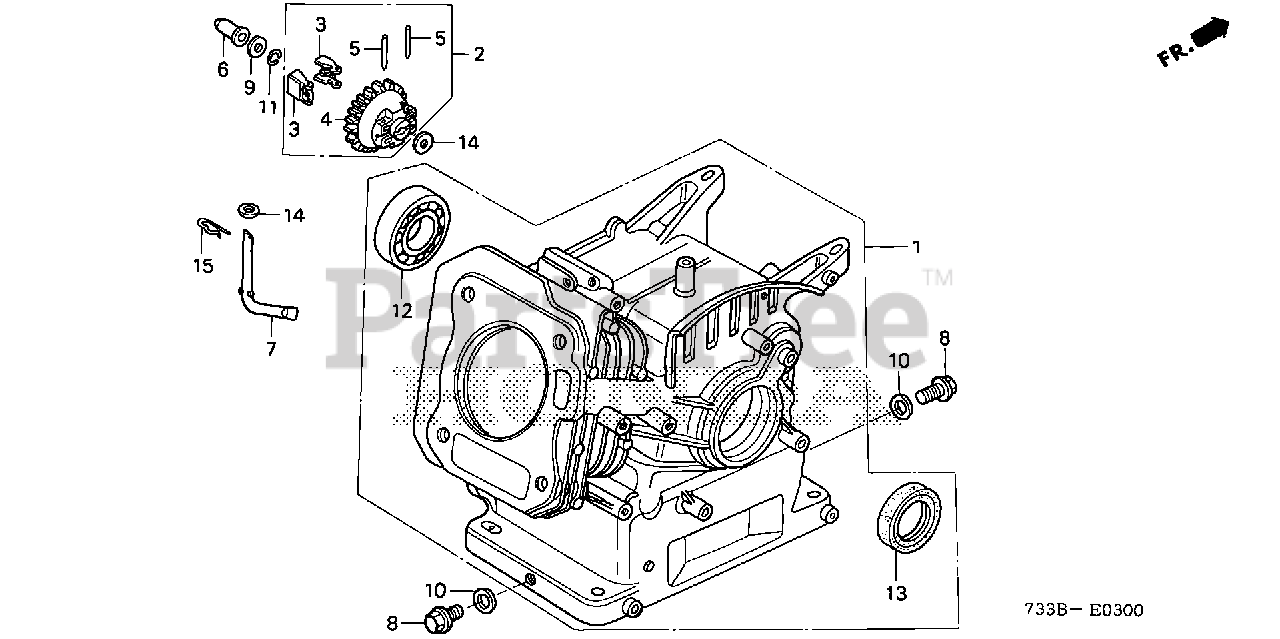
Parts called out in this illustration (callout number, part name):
1	CYLINDER ASSY.
2	GOVERNOR ASSY.
3	WEIGHT, GOVERNOR
4	HOLDER, GOVERNOR WEIGHT
5	PIN, GOVERNOR WEIGHT
6	SLIDER, GOVERNOR
7	SHAFT, GOVERNOR ARM
8	BOLT, DRAIN PLUG
10	WASHER, DRAIN PLUG (10.2MM)
11	CLIP, GOVERNOR HOLDER
12	BEARING, RADIAL BALL (6205TMB) (NTN)
12	BEARING, RADIAL BALL (6205) (NSK)
13	OIL SEAL (25X41X6) (NOK)
14	WASHER, PLAIN (6MM)
15	PIN, LOCK (8MM)
